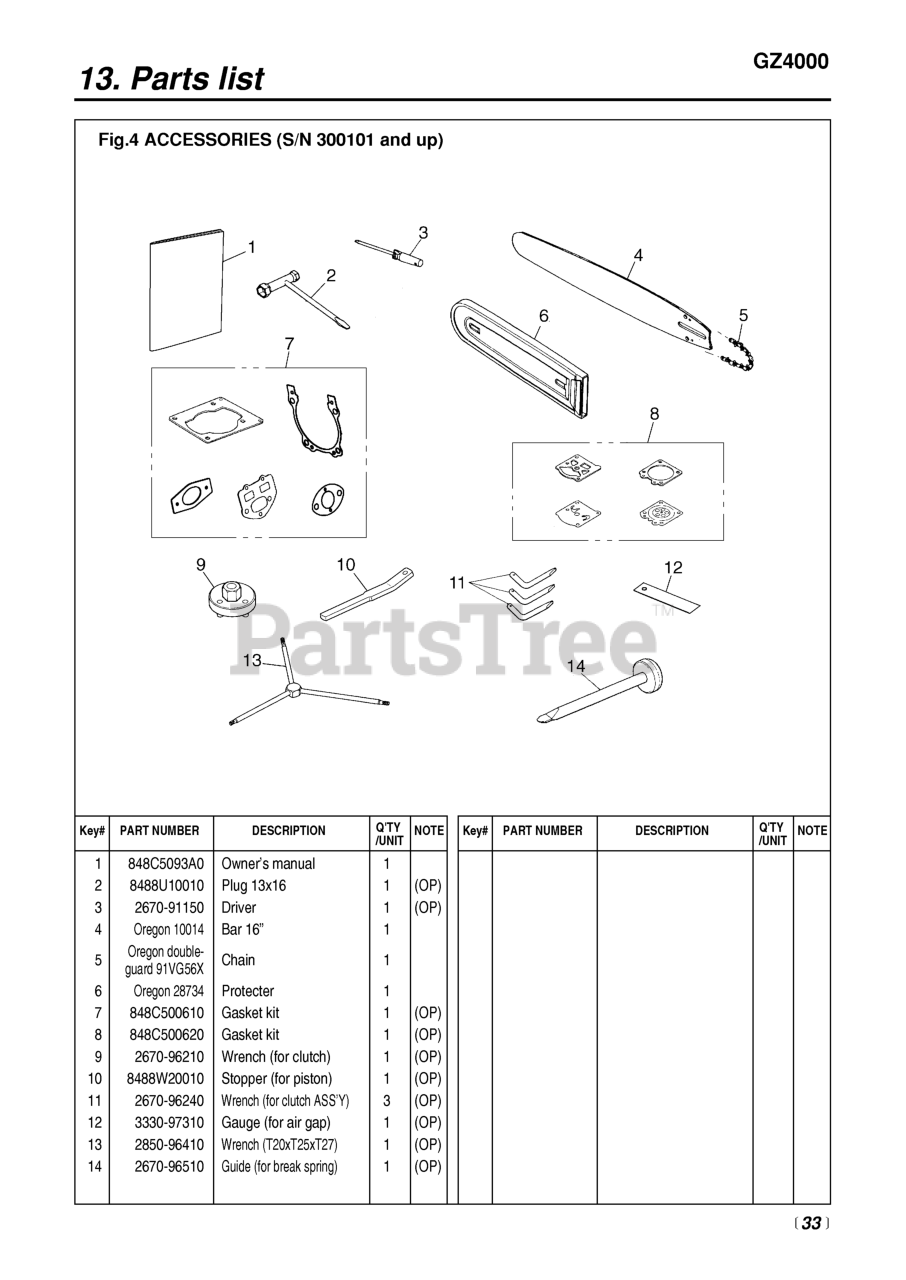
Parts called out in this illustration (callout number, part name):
2	WRENCH
3	SCREWDRIVER
4	BAR 16
6	PROTECTOR (OREGON 28734)
7	GASKET KIT (ENG)
8	GND-27- G-KIT
9	WRENCH (TOOL)
10	STOPPER
11	WRENCH (TOOL)
12	GAUGE (TOOL)
13	WRENCH (RPLS. 2670-96410)
14	GUIDE (TOOL)
